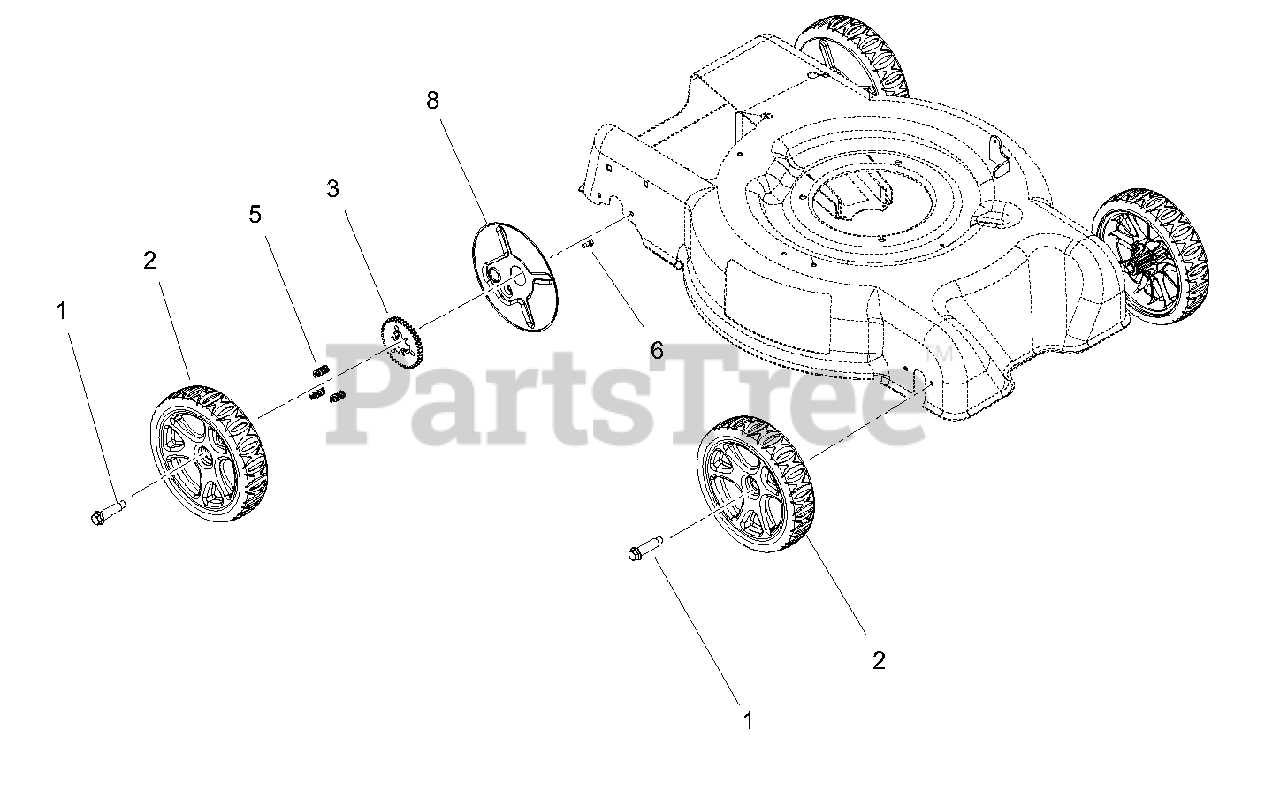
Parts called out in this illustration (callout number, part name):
1	BOLT, WHEEL SHOULDER
2	WHEEL-8.5" WBLM ASSY
3	GEAR, WHEEL
5	SCR-TAP 12-14X.75PLSTITE @BLZC
6	@SCR-TAP .25-20X.37 HWH YWZ TR
8	COVER, WHEEL-ARIENS LM SPECIAL
